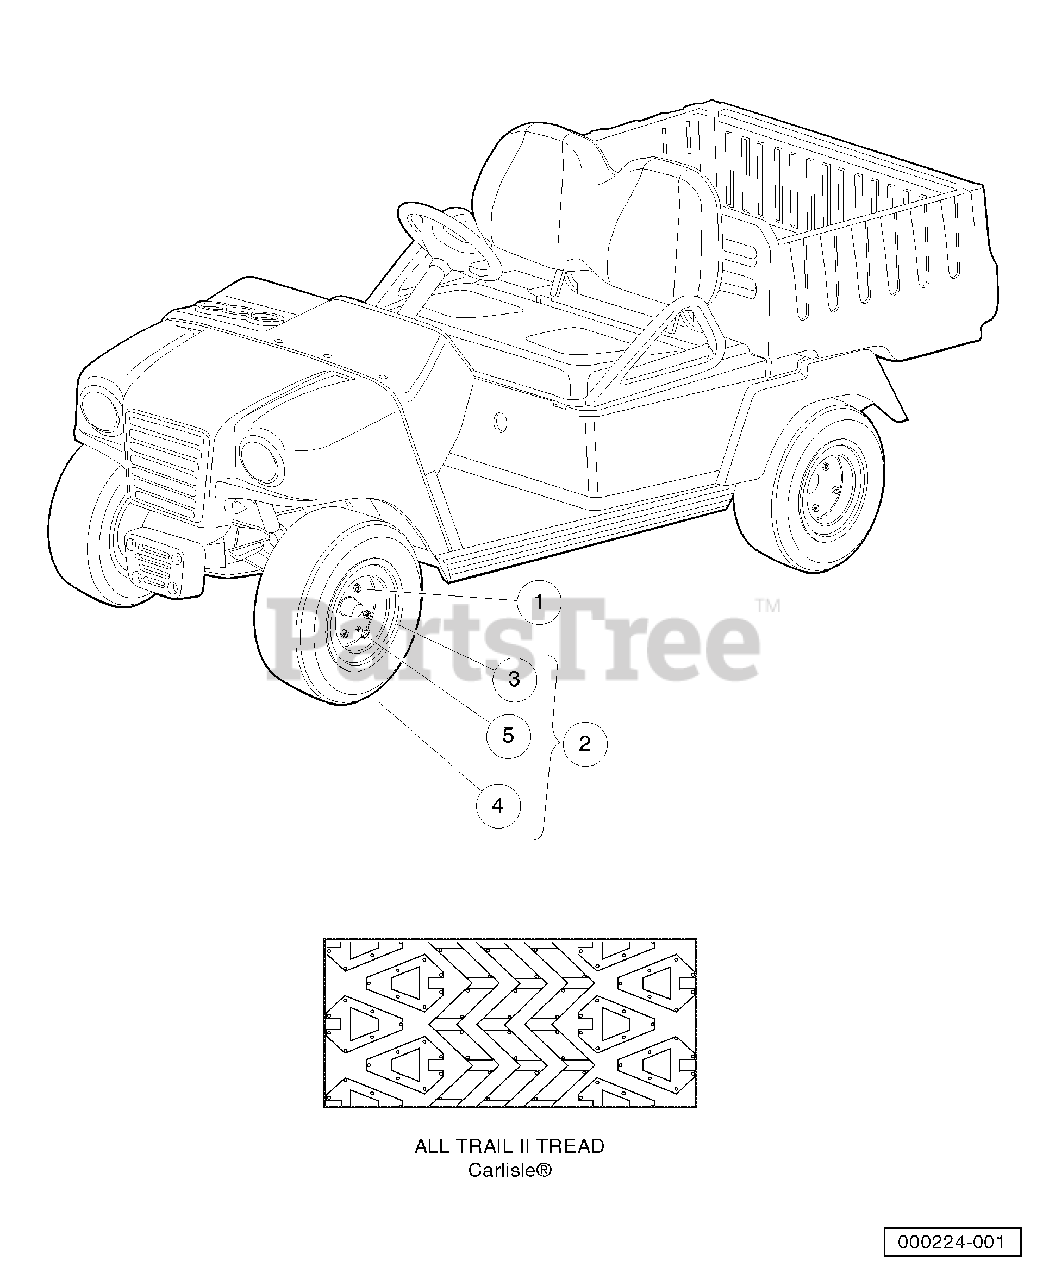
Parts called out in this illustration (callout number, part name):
1	.500-20 Unf Lug Nut
2	Tire Assembly, All Trail II
3	Wheel Rim, Gray
4	Tire, Unmounted, All Trail II
5	Valve Stem
